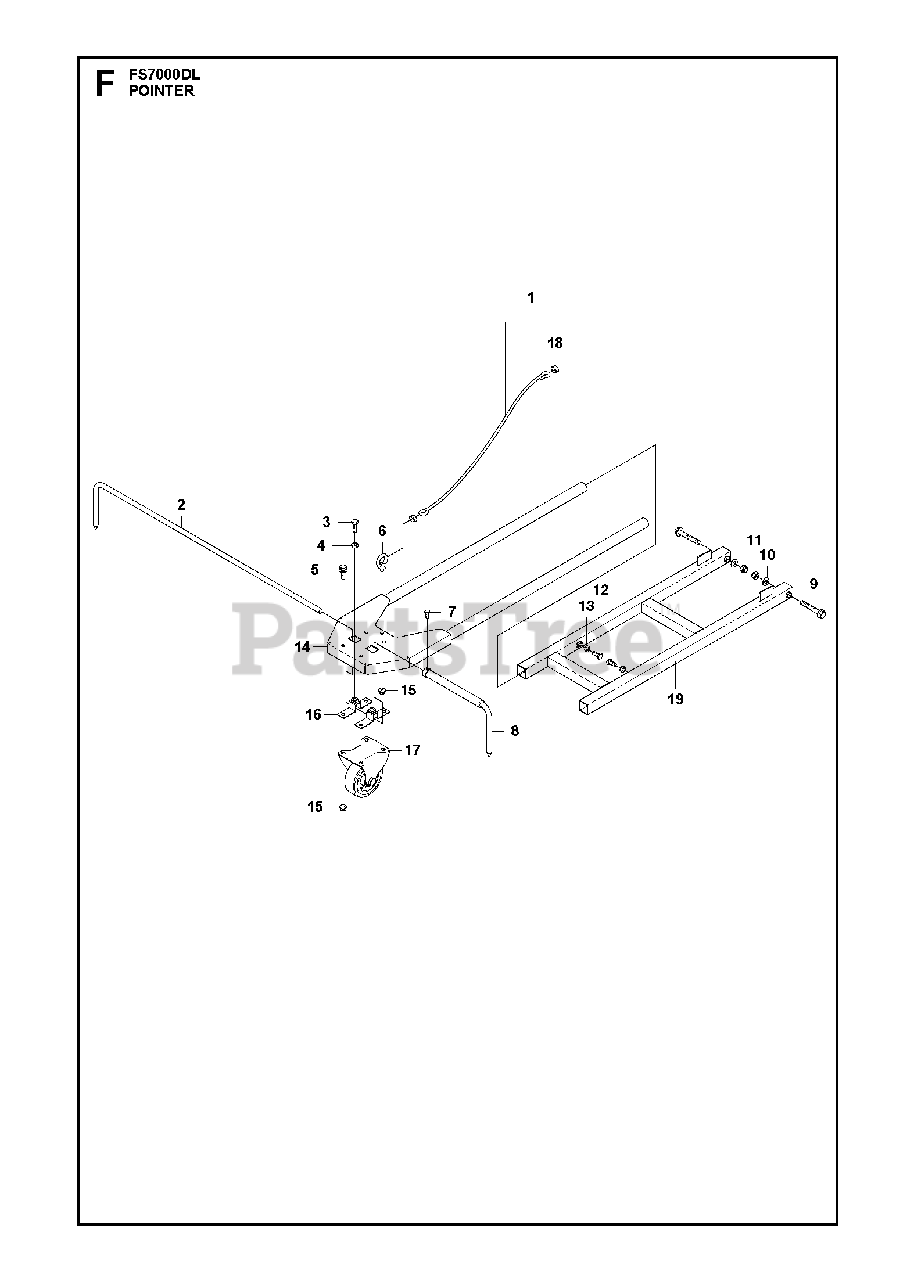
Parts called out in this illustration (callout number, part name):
4	HEXAGON NUT
7	SCREW EHHM
10	WASHER
11	HEXAGON LOCKING NUT
13	HEXAGON NUT
15	HEXAGON NUT FLANGE
